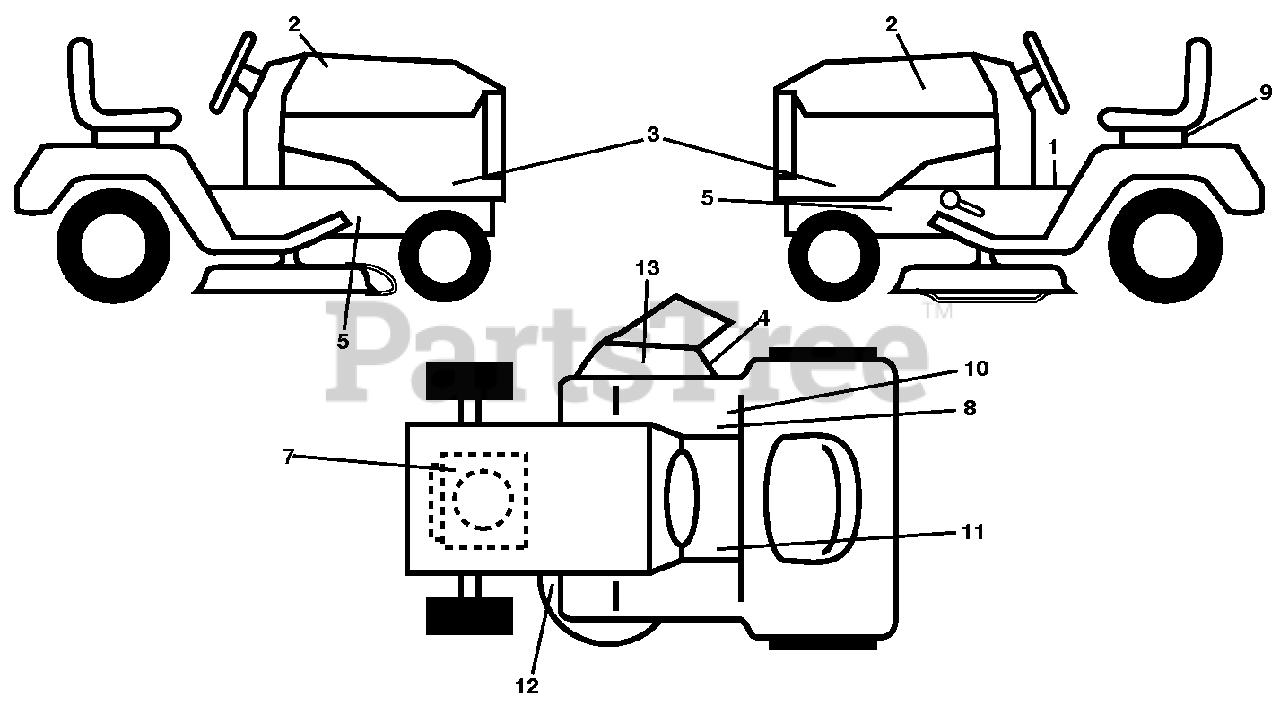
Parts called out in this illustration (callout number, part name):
1	LABEL
2	RP.DECAL.BADGE.170MM.TEXTLOGO
4	DECAL, DEFLECT WARNING
7	DECAL
8	DECAL PARK BRAKE
9	DECAL BTRY SYMBOLS
10	DECAL
11	DECAL
12	DECAL V BELT SCHEMATIC
13	DECAL.INTERNATIONL.CUTFINGER
